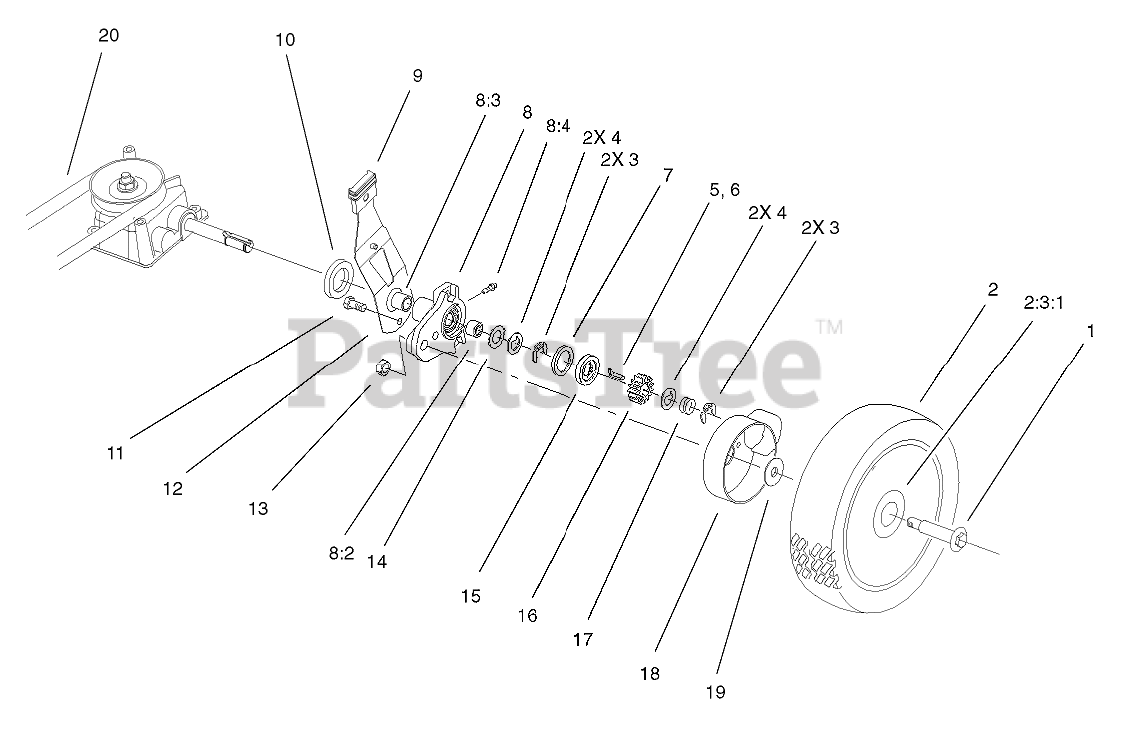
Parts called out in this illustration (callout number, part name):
1	BOLT-SHOULDER
2	WHEEL ASM
2:3:1	BUSHING
3	RING-CLIP, LOCKING
4	WASHER-THRUST, KEYED
5	KEY-ROCKING, RH
6	KEY-ROCKING, LH
7	RING-FRICTION
8	PIVOT ARM ASM
8:2	BUSHING
8:3	BUSHING
8:4	FITTING-GREASE
9	KNOB-ARM
10	CAP-END
11	SCREW-HWH
12	SPRING ARM ASM
14	WASHER-ARM, PIVOT
15	WASHER-CLUTCH
16	GEAR-PINION
17	SPRING-COMPRESSION
18	COVER-WHEEL
19	SPACER-COVER, WHEEL
20	BELT-V
